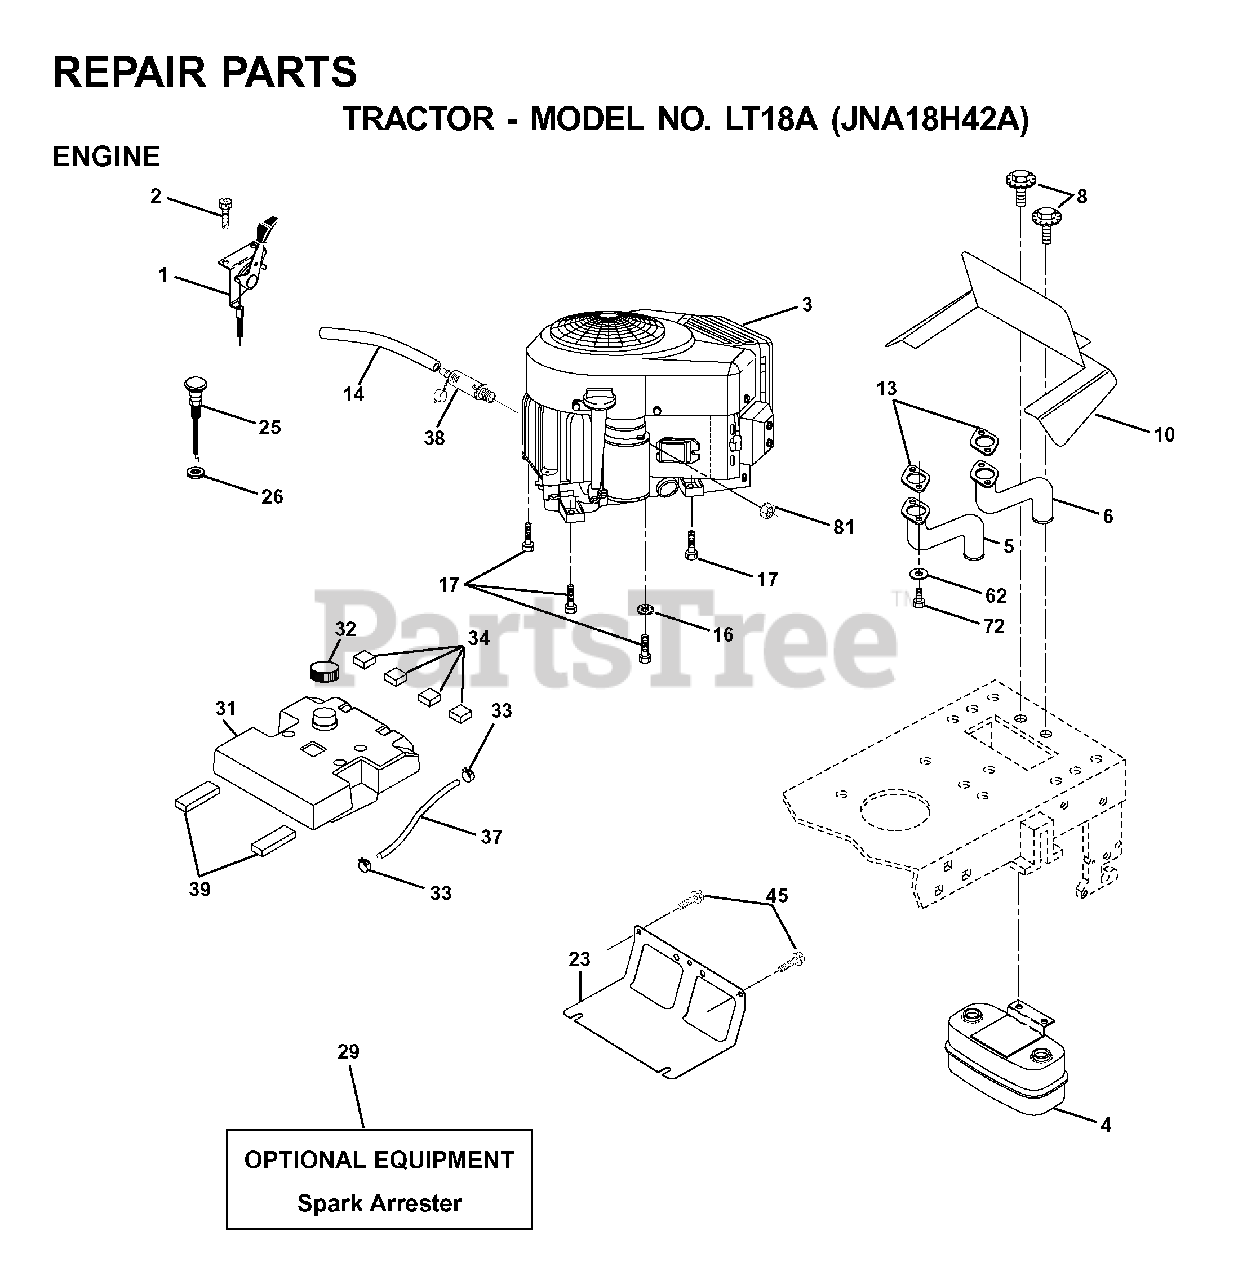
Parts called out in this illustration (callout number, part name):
1	CONTROL, THROTTLE
2	SCREW LT
4	MUFFLER.TWIN.CYL.LOW.TONE
5	EXHAUST TUBE RH
6	TUBE MANIFOLD LH
8	BOLT, 5/16-18 X 1 3/4
10	SHIELD.BROWNING.B&S
13	GASKET.MUFFLER
14	TUBE, DRAIN OIL ASM.
16	LOCKWASHER
17	SCREW LT
23	SHEILD.BROWNING.DBR.GUARD
25	CONTROL, CHOKE
26	NUT KEPS 3/8 - 24 UNF
29	ARRESTER SPARK (OPTIONAL)
31	TANK.FUEL(3.5.GAL)
32	FUEL CAP
33	HOSE CLAMP
34	PAD-SPACER LT
37	LINE.FUEL.20
38	PLUG, OIL DRAIN EASY
39	PAD IDLER TI
45	SCREW, 3/8-16X3/4
62	LOCKWASHER
72	SCREW
81	NUT
